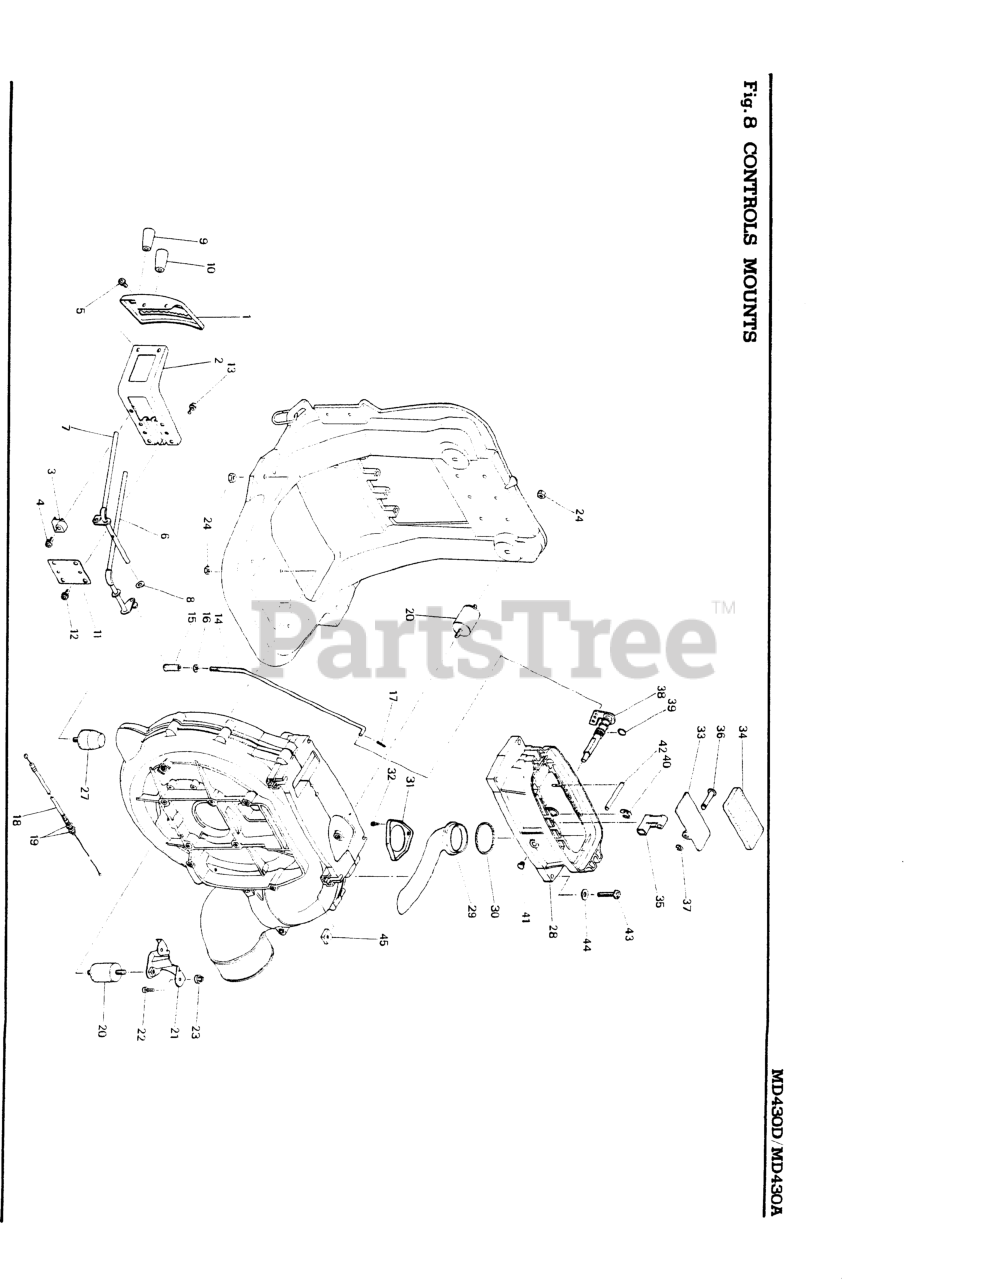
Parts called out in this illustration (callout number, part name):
1	INDICATOR
2	BRACKET
4	SCREW, M5 x 12
5	SCREW, M5 x 12
7	LEVER (B)
8	WASHER (NO LONGER AVAIL)
11	PLATE (NLA)
12	SCREW, M5 x 12
13	SCREW, M5 X 20
16	NUT, M5 X 4
18	CABLE, THROTTLE
19	NUT, M6 X 5
22	SCREW, M5 x 16
23	WASHER
24	NUT, M6 X 5
29	GUIDE PIPE
31	COVER (RPLS -13140) (NLA)
32	SCREW, M4 x 10
33	SHUTTER (NLA)
34	COVER, SHUTTER (NLA)
35	ARM (NLA)
38	SHAFT (NLA)
40	RING, SNAP
43	BOLT, M6 x 40
44	WASHER, M6 x .8
45	NUT
